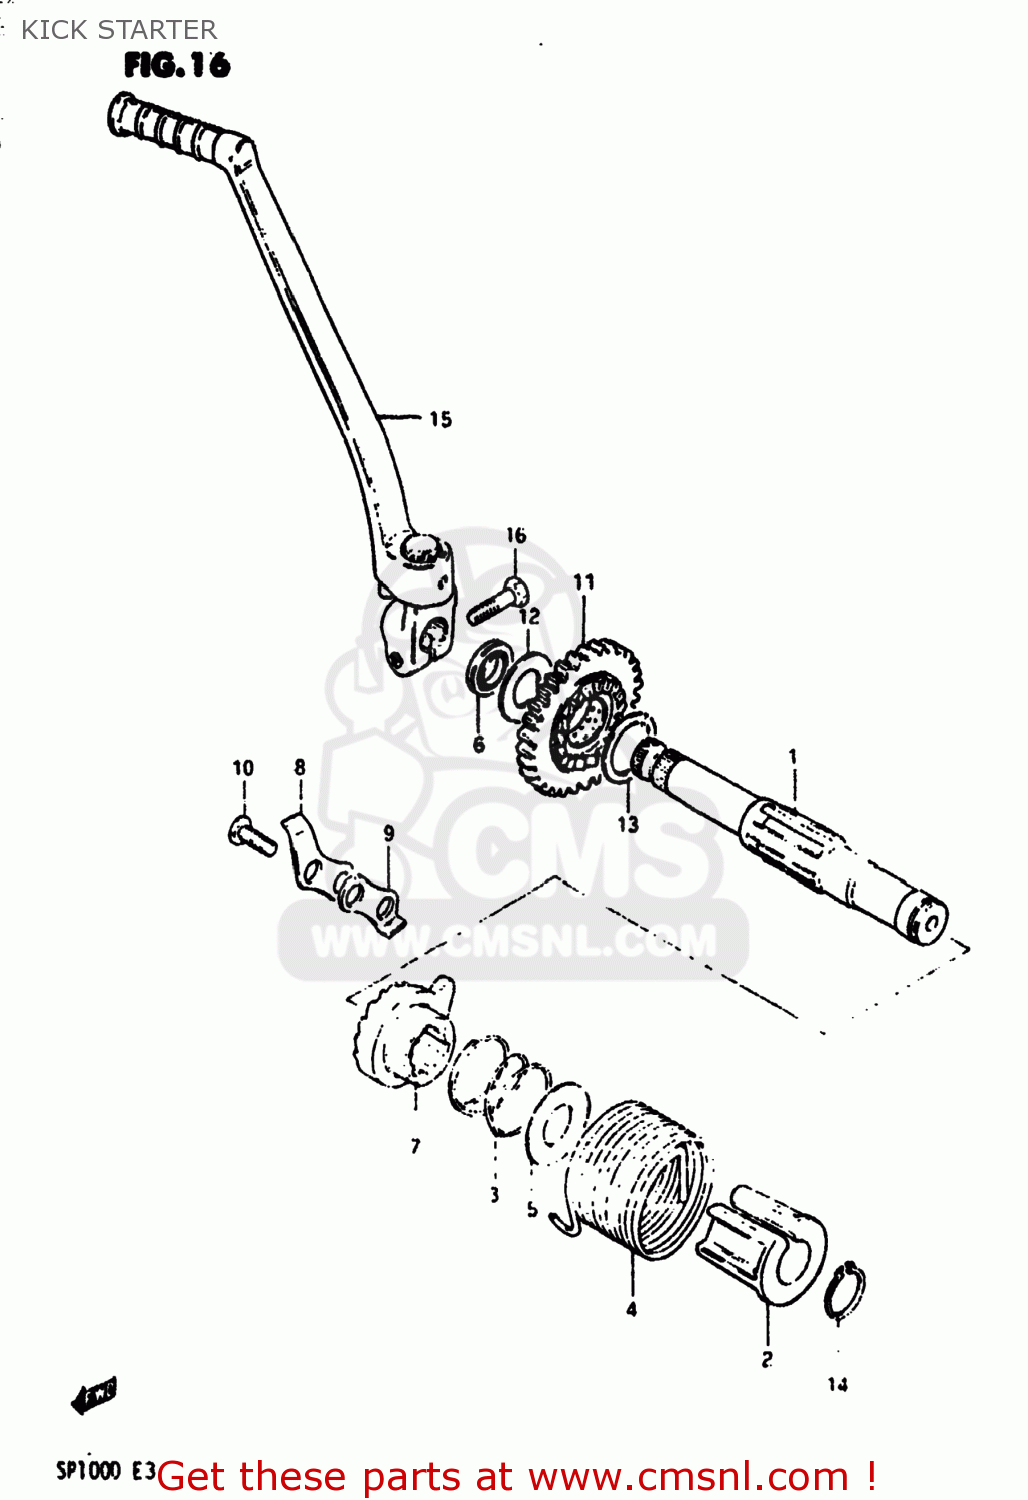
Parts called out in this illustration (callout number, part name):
1	SHAFT,KICK STARTER
2	GUIDE,KICK STARTER SFT SPRING
3	SPRING
4	SPRING
5	WASHER
6	SEAL,OIL(16X24X5)
7	STARTER,KICK
8	GUIDE,KICK STARTER
9	STOPPER,KICK STARTER
10	BOLT
11	GEAR,KICK STARTER DRIVE
12	WASHER(16X30X1)
13	WASHER
14	CIRCLIP
15	LEVER ASSEMBLY,KICK STARTER
16	BOLT 8X25
